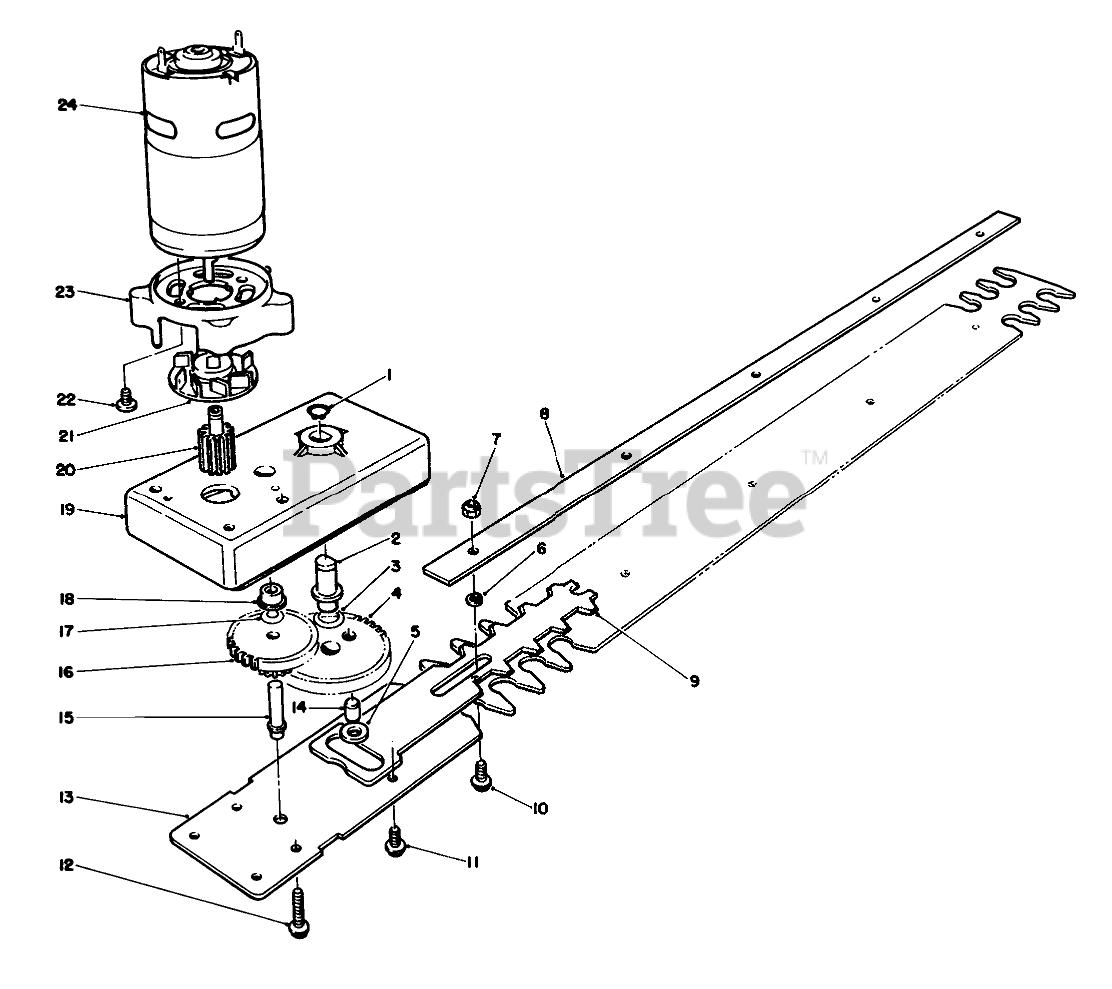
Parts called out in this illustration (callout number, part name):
2	Shaft-Driver
3	WAVE-DRIVER
4	Gear-Drive (Incl. Ref. #14)
5	BUSHING-CAM
6	BLADE-BUSHING
7	NUT-LOCK
8	BLADE-RETAINER
9	BLADE-CUTTING
10	HEX SCREW 8-32X.5
11	SCREW-HWHTF
12	SCREW - #8 X 1-1/4
13	Blade-Bottom
14	Pin-Drive
15	SHAFT-IDLER
16	GEAR-IDLER
17	WAVE-IDLER
18	Bearing-Idler
19	Housing-Gear Assembly (Incl Ref. 2 & 18)
20	Gear-Motor
21	Fan-Motor
22	Screw-Phil. Pan Hd.
23	Support-Motor
24	Motor Assembly (Incl. Ref. #20-23)
